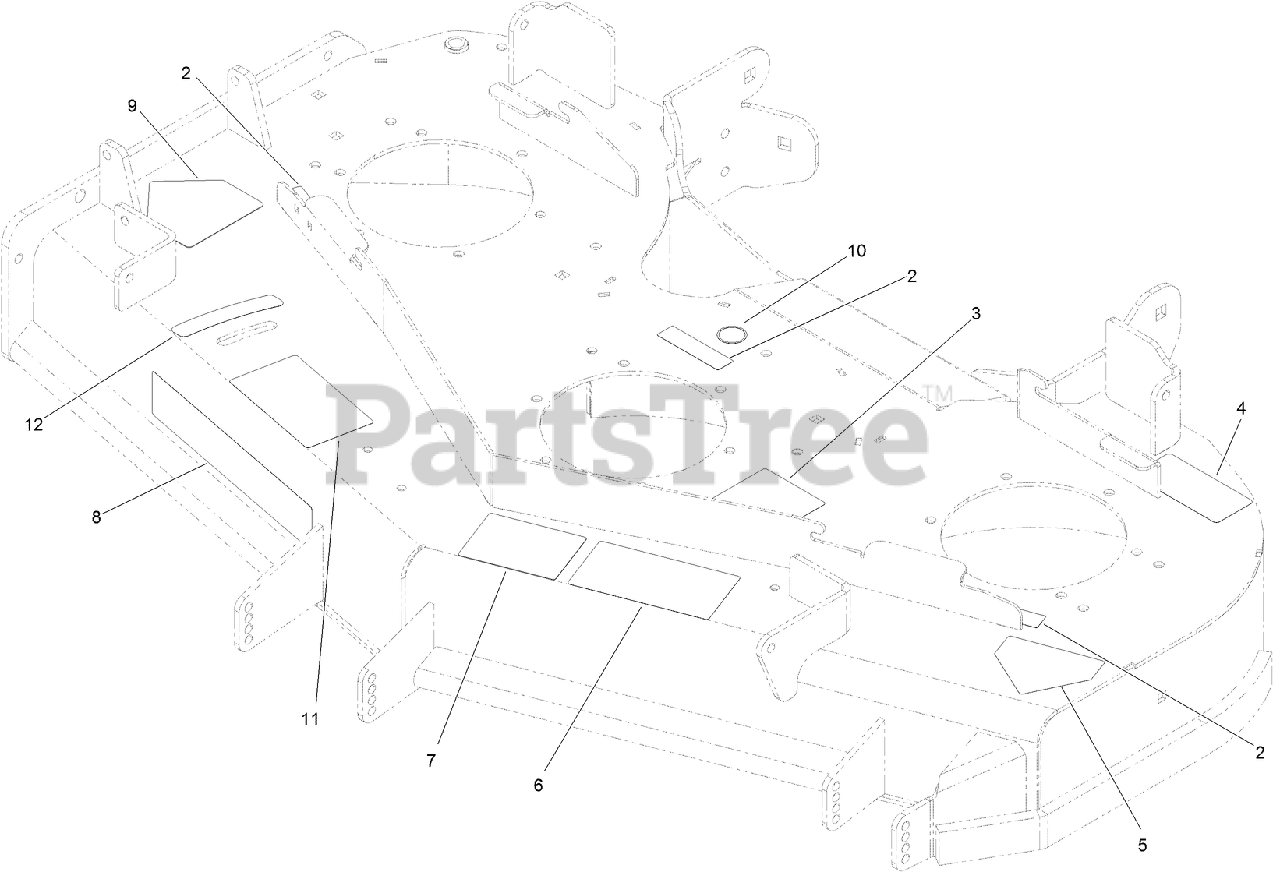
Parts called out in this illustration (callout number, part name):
2	DECAL-COVER, MISSING
3	DECAL-ROUTING, DECK BELT
4	DECAL-TORQUE
5	DECAL-DANGER
6	DECAL-DANGER, THROWN OBJECT
7	DECAL-SCALP, ANTI
9	DECAL-DANGER
10	DECAL-GREASE
11	DECAL-ADJUSTMENT, BAFFLE
12	DECAL-SETTING, BAFFLE
